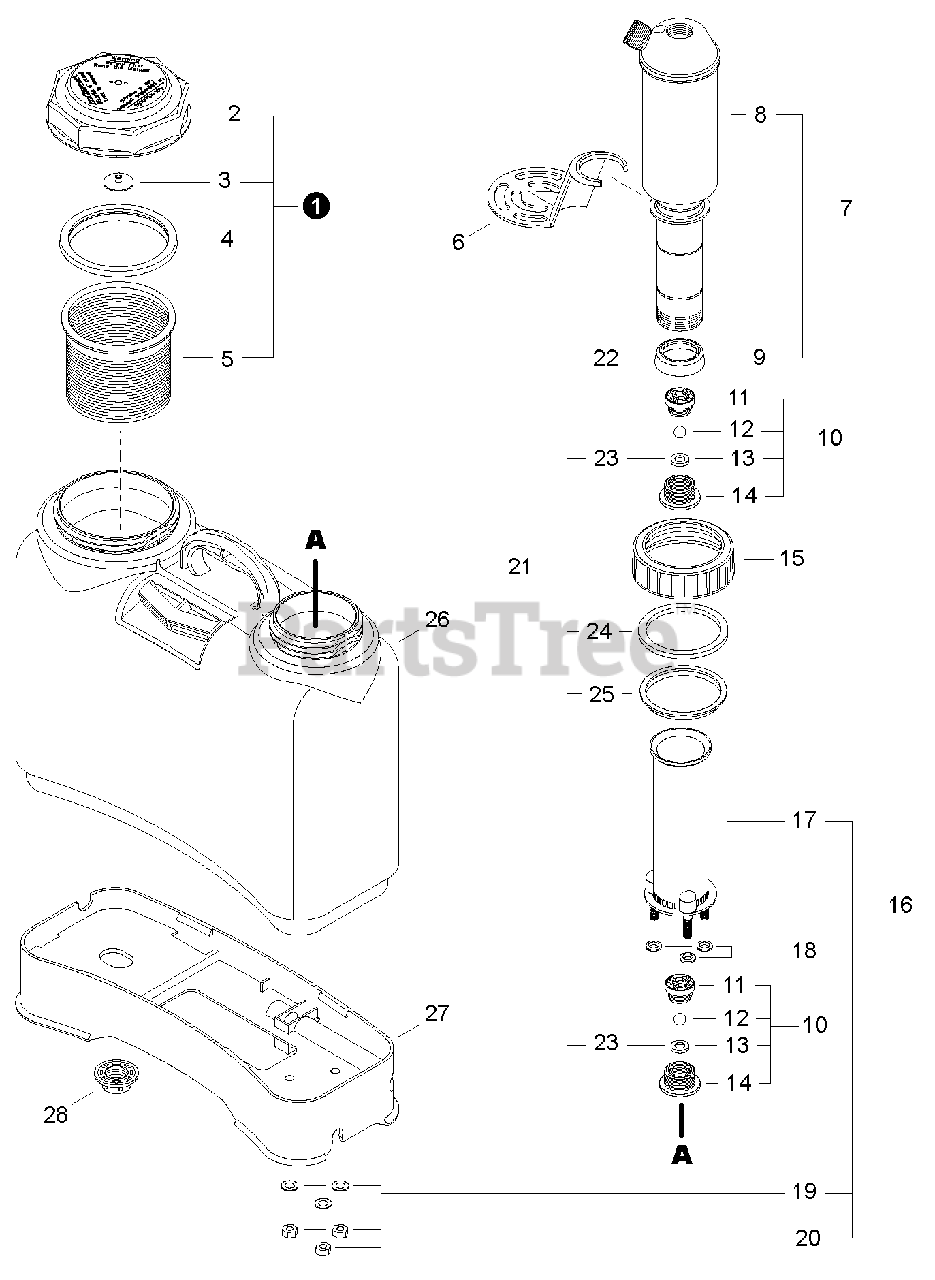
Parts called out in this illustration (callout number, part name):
1	CAP KIT, TANK
2	CAP, TANK
3	VALVE, CHECK - CAP
4	GASKET, BASKET
5	BASKET, FILTER
6	AGITATOR
7	CHAMBER KIT, PRESSURE
8	CHAMBER, PRESSURE
9	CUP, PLUNGER
10	VALVE ASSY, CHECK
11	BODY, VALVE
12	BALL, VALVE
13	WASHER
15	RING, LOCKING
16	CYLINDER KIT, PISTON
17	CYLINDER
18	GASKET, STUD
19	WASHER
21	GASKET KIT, PUMP
22	CUP, PLUNGER
23	WASHER
24	WASHER, FELT
25	GASKET, CHAMBER
26	TANK, SPRAYER
27	BASE, TANK
28	NUT, TANK
